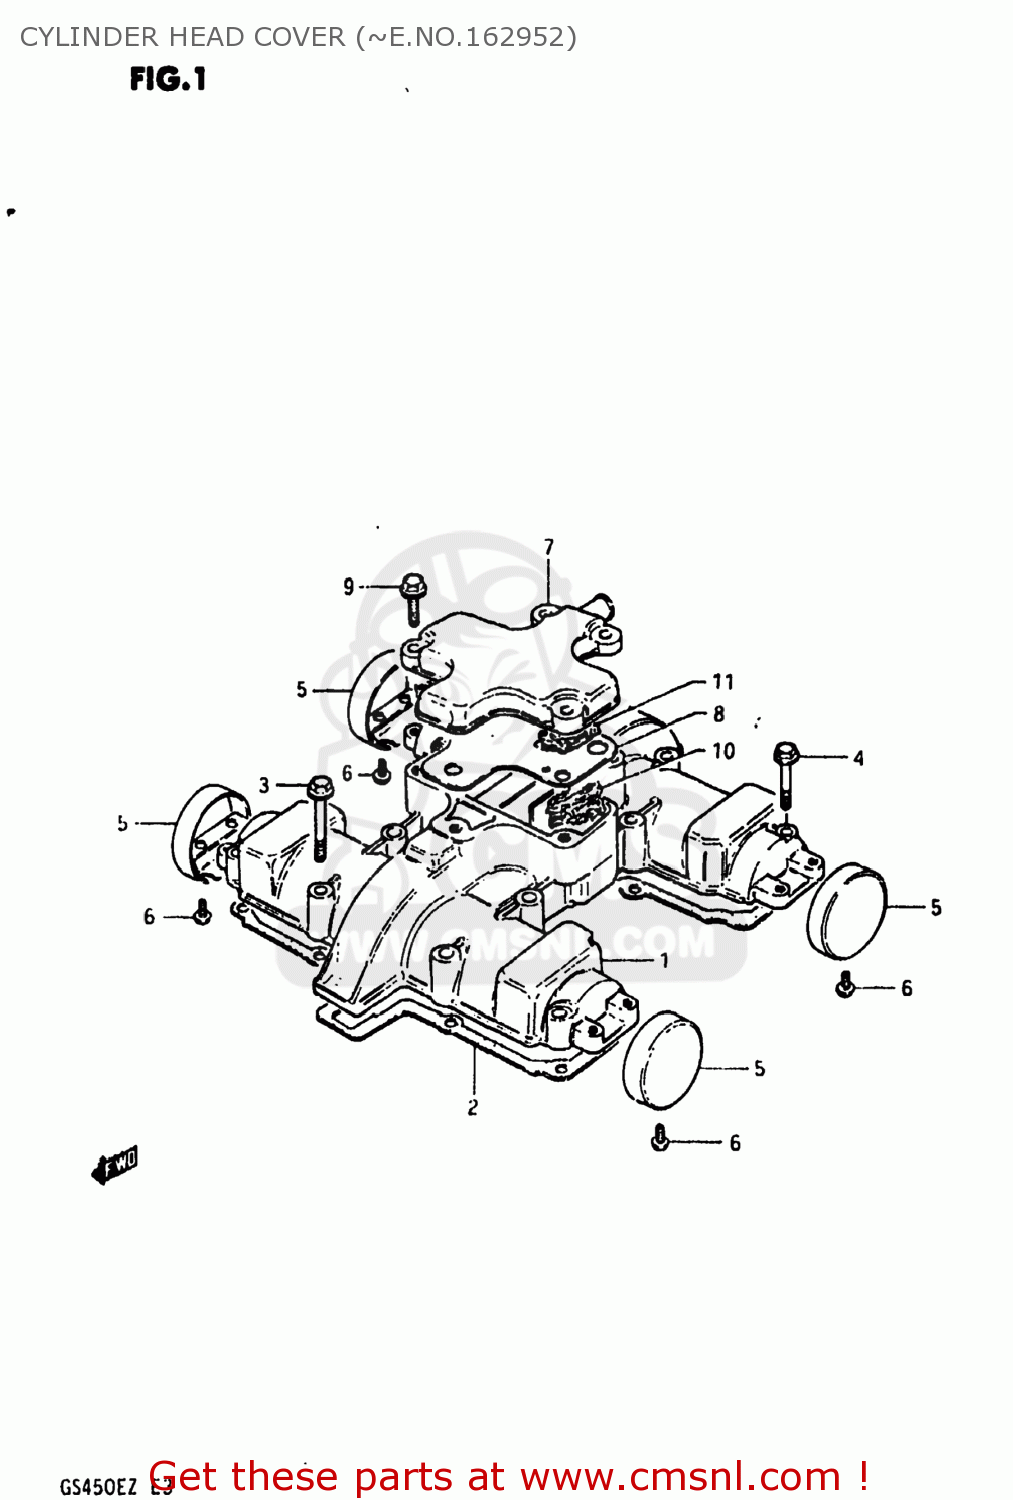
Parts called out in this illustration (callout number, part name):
1	COVER,CYLINDER HEAD
2	GASKET,CYLINDER HEAD COVER
3	BOLT
4	BOLT
5	CAP,CYLINDER HEAD COVER
6	SCREW
7	COVER,BREATHER
8	GASKET (MCA)
9	BOLT,REAR
10	COVER,BREATHER
11	SEPARATOR,OIL BREATHER
